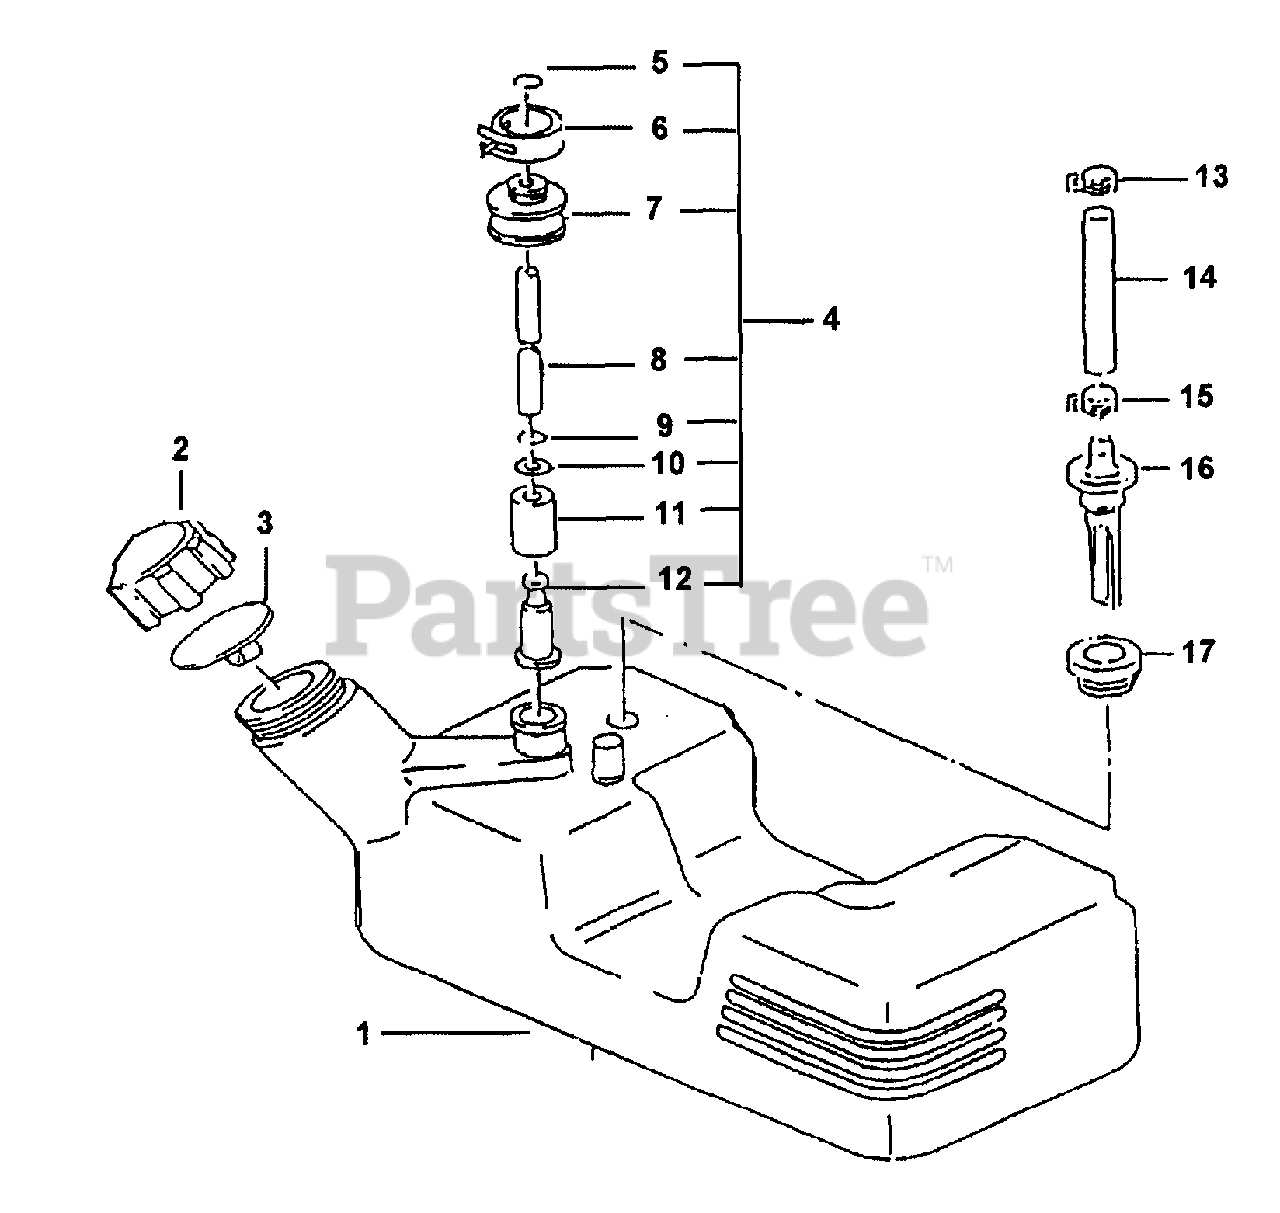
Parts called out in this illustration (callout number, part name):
1	FUEL TANK ASSY.
3	BREATHER, TANK CAP
4	FUEL FILTER ASSY.
8	FUEL TUBE
11	FUEL FILTER
16	FUEL FILTER
